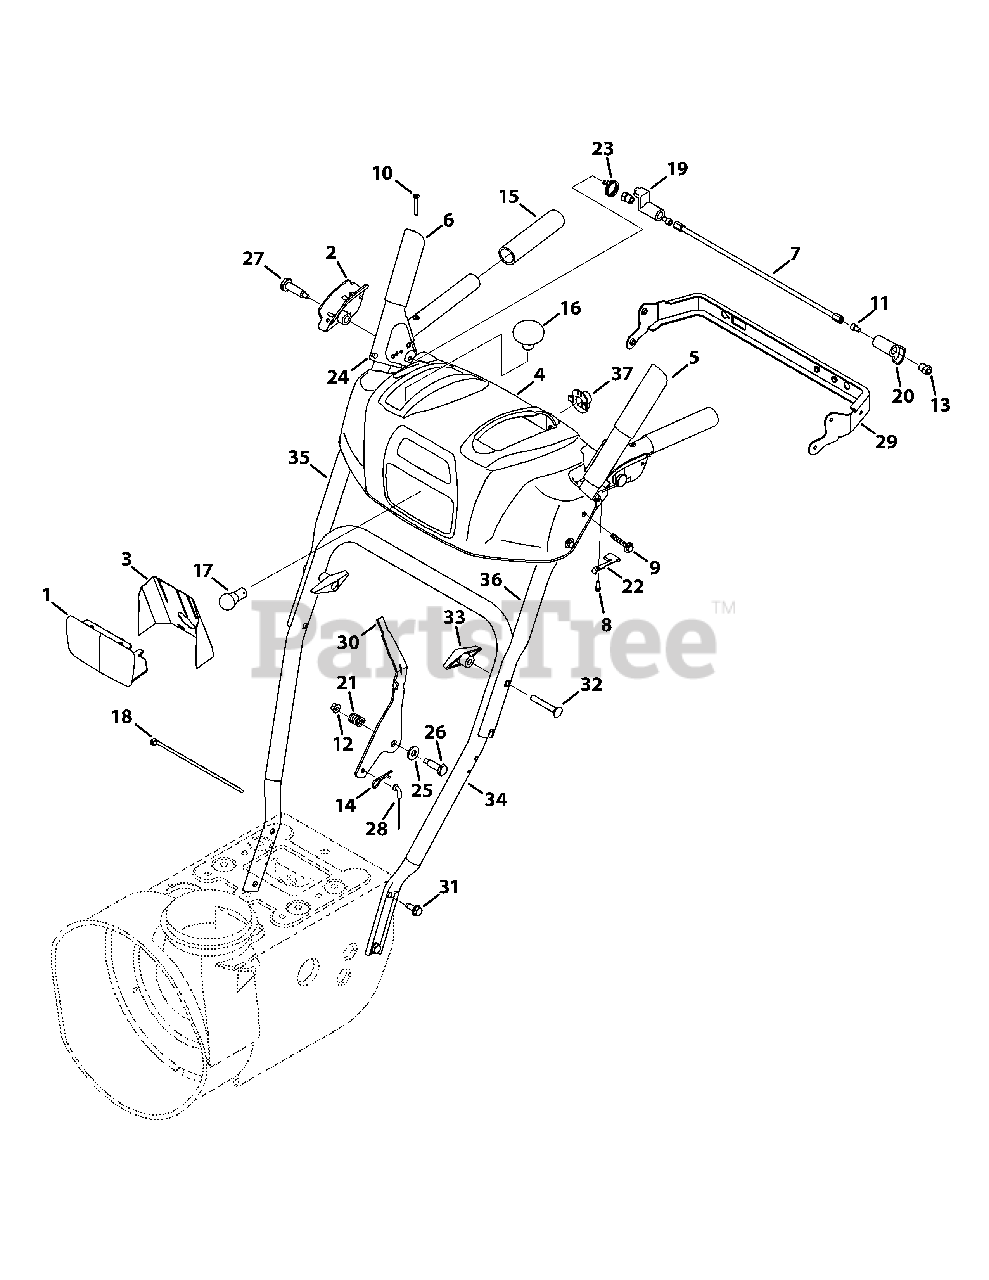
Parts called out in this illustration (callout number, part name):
2	Handle Clutch Lock - RH
2	Handle Clutch Lock - LH
3	Lens Reflector Label
4	T-Style Panel Ass’y, (inc. Ref. 1 & 3)
5	Handle Engagement Assembly LH
6	Handle Engagement Assembly RH
8	Screw, Plastite, 8-16 x .50
9	Screw, 1/4-20 x 1.625
10	Screw, #10-24 x 1.375
11	Screw, Socket, 1/4-20 x .50
12	Flange Lock Nut, 1/4-20
13	Shoulder Nut, 1/4-20
14	Click Pin
15	Handle Grip
16	Shift Knob
18	Cable Tie
20	Clutch Lock Cam
21	Compression Spring
22	Clutch Lock Spring
23	Torsion Spring
24	Rubber Bumper
25	Flat Washer, .385 x .87 x .06
26	Shoulder Screw, .374 x 1.05
27	Shoulder Screw, 1/4-20 x 1.345
28	Speed Selector Cable
29	Panel Bracket
30	Shift Lever
31	Screw, 5/16-18 x .750
32	Carriage Screw, 5/16-18 x 2.25
33	Wing Knob
34	Lower Handle
35	Upper Handle RH
36	Upper Handle LH
37	Light Socket
